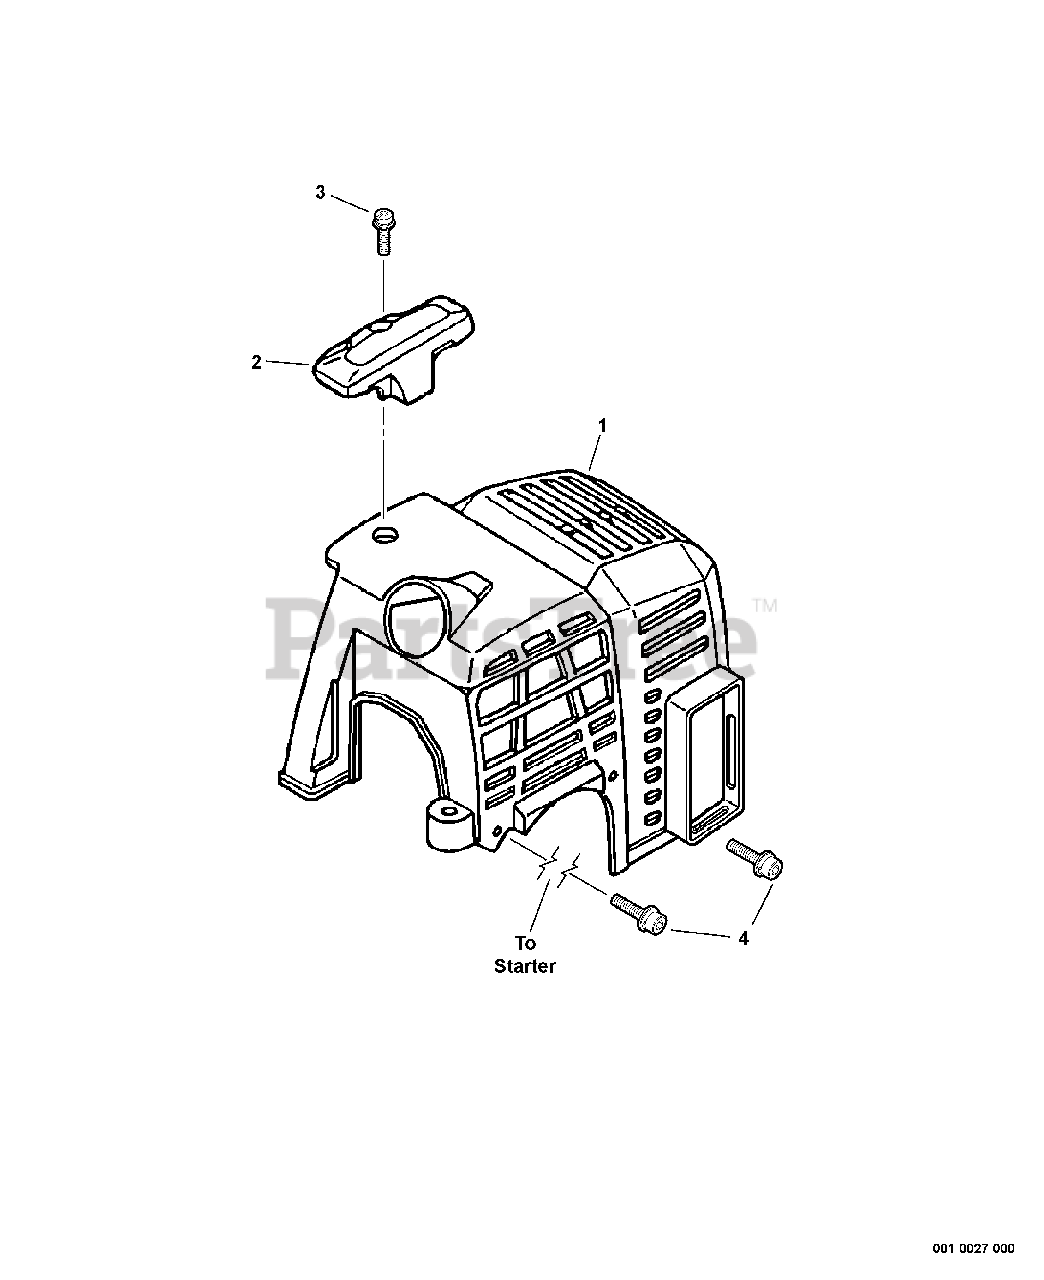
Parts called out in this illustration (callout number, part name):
1	COVER, ENGINE
2	GUARD - TOP
3	SCREW - 5X16
4	SCREW - 4X16
